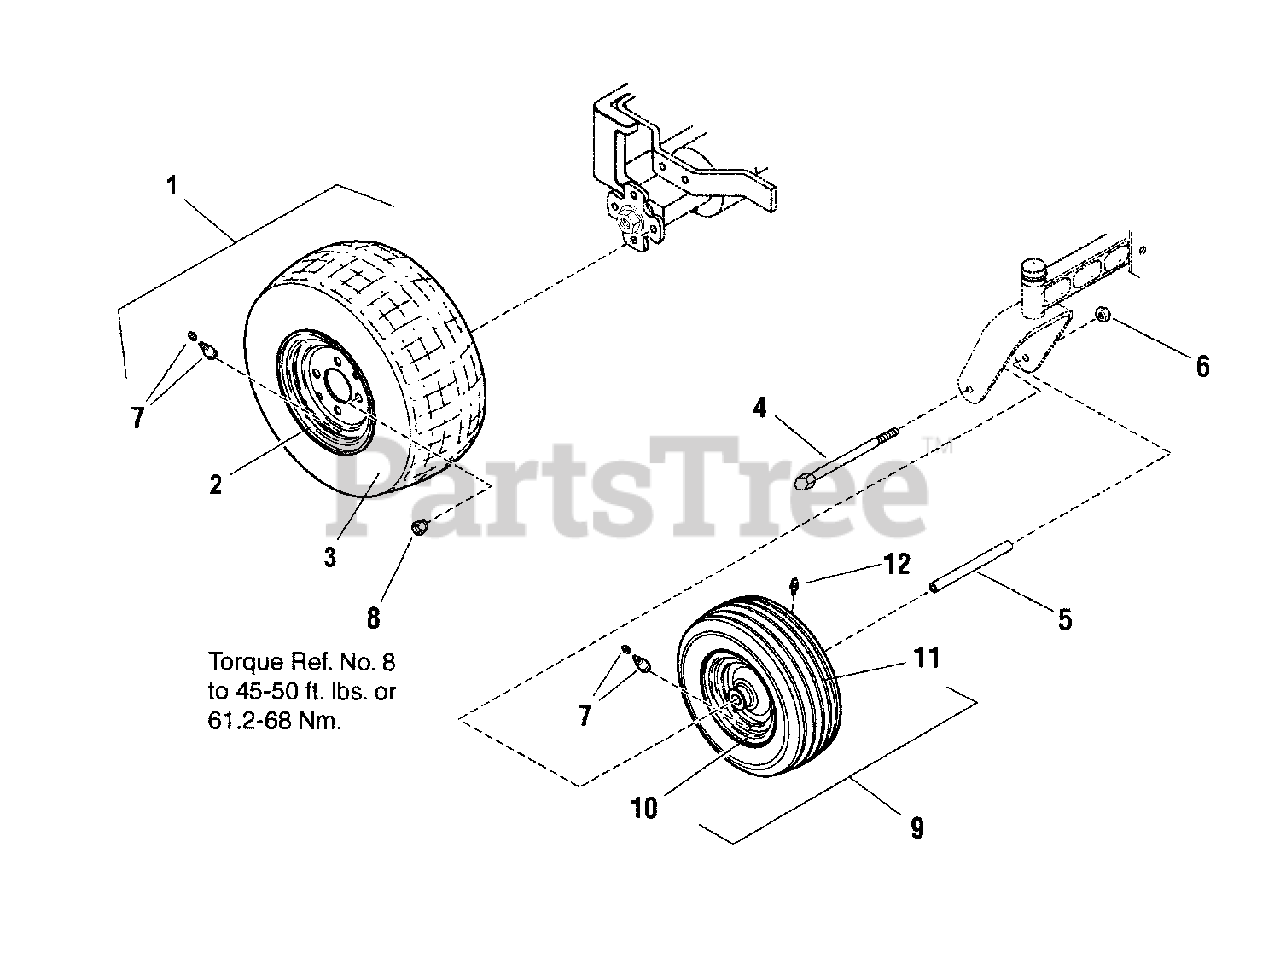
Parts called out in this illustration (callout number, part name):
1	ASSY, Wheel & Tire, 18 x 8.50-8 "Superturf" (incl. 2 & 3)
2	RIM, 18 x 8.50-8, 4 Hole
3	TIRE, 18 x 8.50 4 Ply "Superturf"
4	SCREW, 7/16-14 x 6" Hex Head Cap, GR5
5	TUBE, Caster
6	NUT, 7/16-14 Hex Center Lock
7	VALVE STEM & CAP, Air
8	NUT, 1/2-20 for Wheel Bolt - Silver
9	ASSY, Wheel & Tire 11 x 4-5 (Caster)
10	RIM w/Bushings
11	TIRE, 11 x 4-5
12	FITTING, Lube (45° 8Mx1M)
